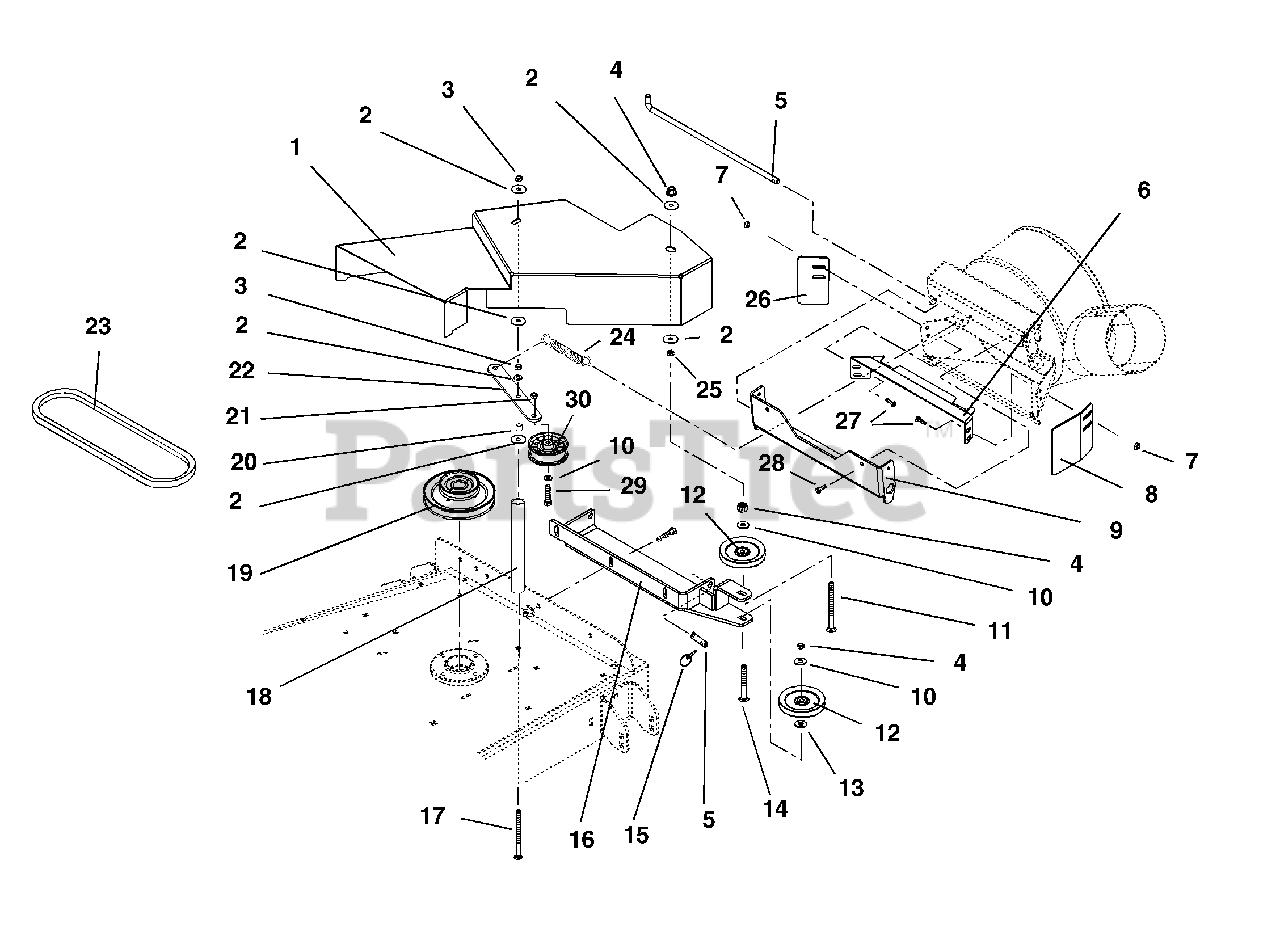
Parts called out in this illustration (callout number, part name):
1	Weldment, Belt Guard
2	Washer-Flat-Steel .38 x 1.50 x .062
3	Nut-Locking-Nylon .312-18
4	Nut-Locking-Nylon .38-16
5	Rod-Pivot
6	Guard, Pump Inlet
7	Nut-Locking-Top-Flange .25-20
8	Bracket, Formed
9	Weldment, Blower Mount
10	Washer-Flat-Steel .438 x 1.00 x .083
11	Bolt-Round Head Square Neck .38-16 x 2.5 Grade 5
12	Idler-V 4.00 x .38
13	Washer-Flat-Steel .406 x 1.00 x .188
14	Bolt-Round Head Square Neck .38-16 x 1.75 Grade 5
15	Pin-Klik 1.00 x .188 x 1.25
15	(Gravely Part Number)
16	Weldment, Pivot Mount Bracket
17	Bolt-Round Head Square Neck .31-18 x 5 Grade 5
18	Spacer .625 x 3.25
19	Pulley, Double V 3.50/5.25 Dia.
20	Spacer .380 x .503 x .281
21	Nut-Locking-Top-Flange .38-16
22	Arm, Idler
23	V-Belt, 48-780 78" Outer Circle
24	Spring-Tension .069 x .62 x 3.50
24	(Gravely Part Number)
25	Nut-Hex-Jam .375-16
26	Bar, Extension
27	Bolt-Round Head Square Neck .25-20 x .75 Grade 5
28	Screw-Tapping .25-20 x .50 Hex Washer Head Thread Rolling
29	Bolt-Hex .38-16 x 1.75 Grade 5
30	Idler-Flat 3.00 x .38
